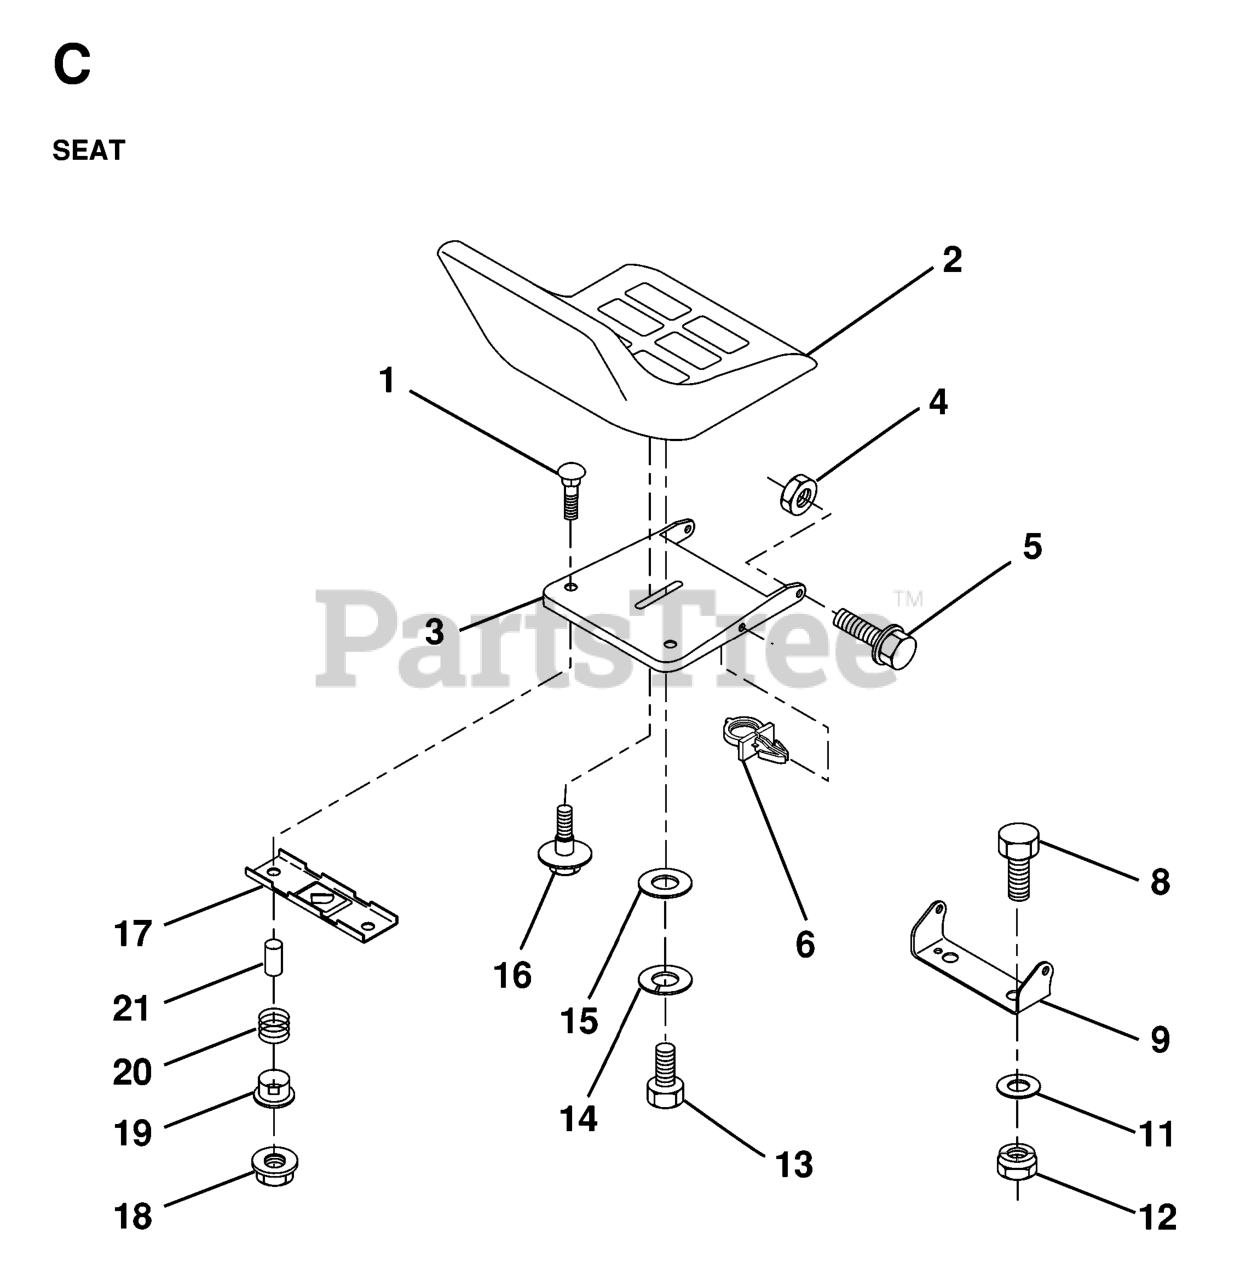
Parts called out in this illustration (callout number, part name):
1	BOLT.ROUND.HEAD.SQUARE.NECK
2	SEAT
3	PAN, SEAT
4	NUT.71038.31-18.HEX.NYLOCK
5	BOLT SHOULDER 5/16-18
8	BOLT
9	SEAT PIVOT BRKT
11	WASHER 12/32X2X10GA
12	NUT
13	BOLT
14	LOCKWASHER
16	BOLT,SHOULD
17	BRKT SWITCH
18	NUT T
21	SPACER SPLIT 28X.96
